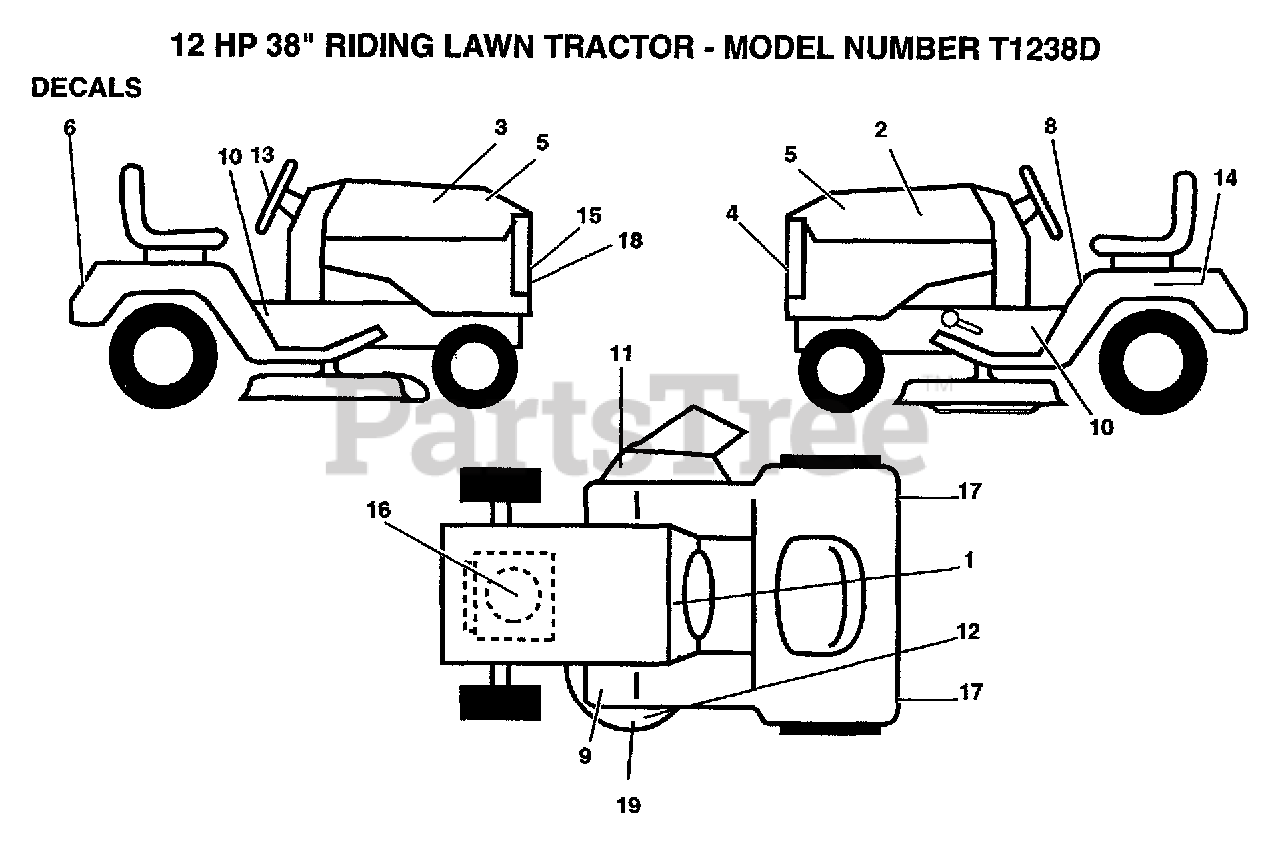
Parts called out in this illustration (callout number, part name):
2	DECAL, HOOD STRIPE LH
3	DECAL, HOOD STRIPR RH
4	"DECAL,GRILL"
5	DECAL HP HOOD
6	"DECAL,FENDER"
8	DECAL
9	DECAL T
11	DECAL WARNING
12	DECAL YT
13	"DECAL,STR WHL T"
14	DECAL
16	DECAL.ENG.271967
17	REFLECTOR-TAIL YT
18	DECAL.STRIPE.GR
